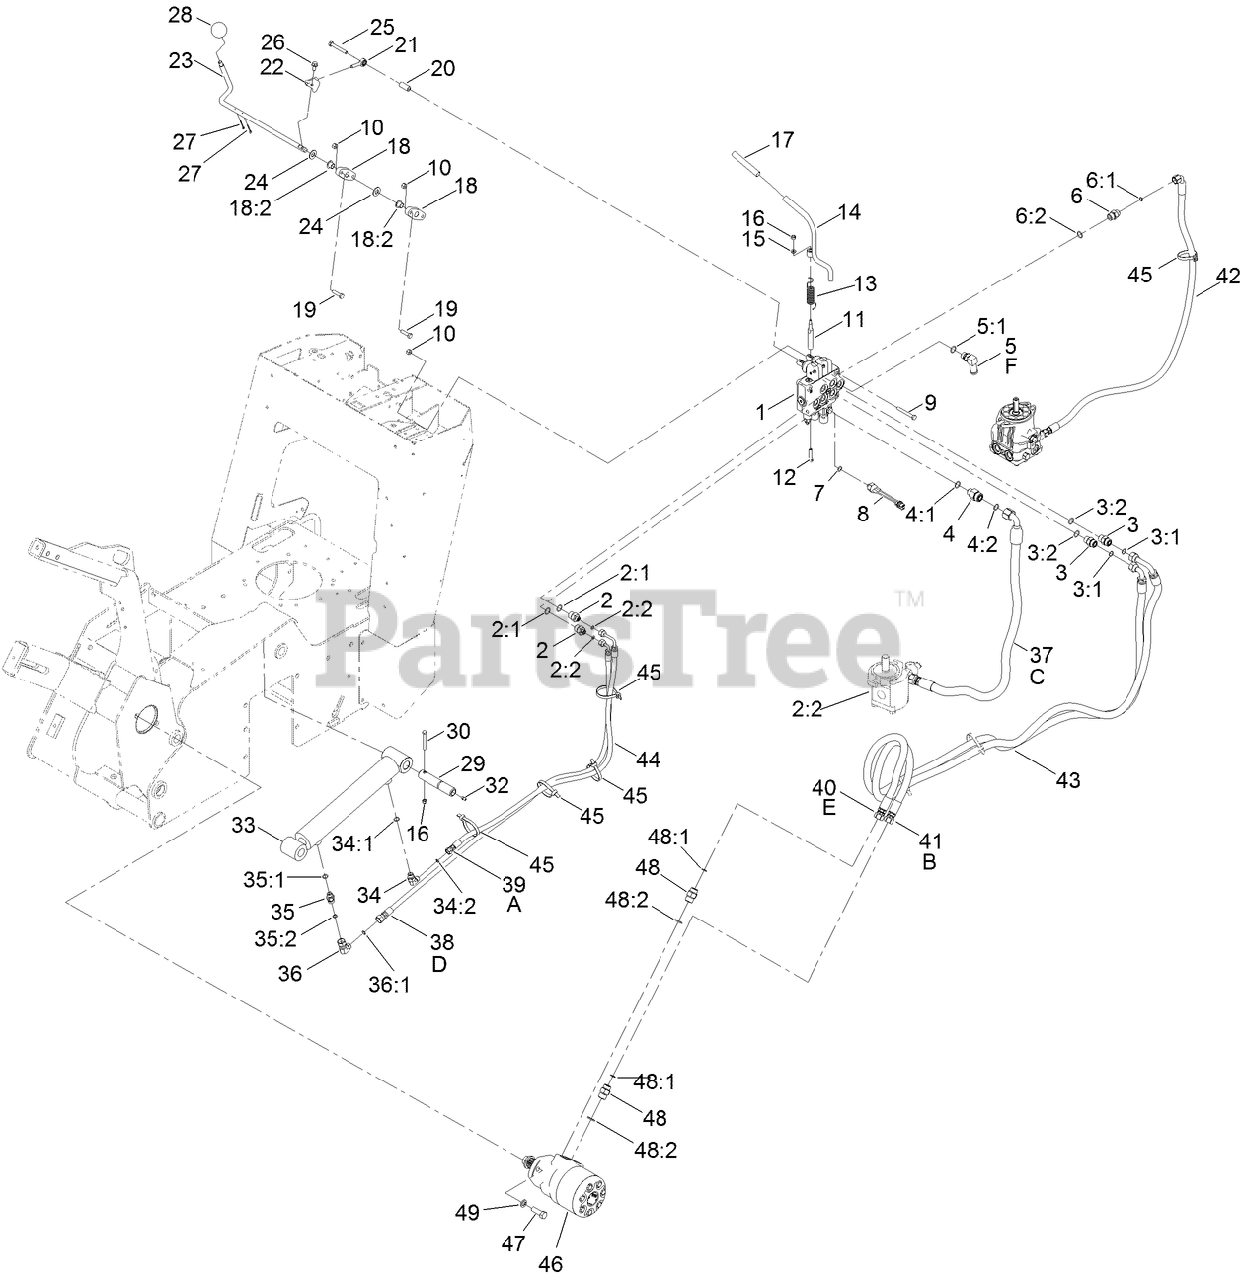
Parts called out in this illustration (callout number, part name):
1	HYD VALVE ASM
2	FITTING-STR
2:1	O-RING
2:2	O-RING
3	FITTING-STRAIGHT
3:1	O-RING
3:2	O-RING
4	FITTING-STRAIGHT
4:1	O-RING
4:2	O-RING
5	FITTING-ELBOW, 90
5:1	O-RING
6	FITTING-STRAIGHT
6:1	O-RING
6:2	O-RING
7	O-RING
8	SWITCH-BALL
9	SCREW-HH
10	NUT-LOCK, NI
11	SPACER-HIFLO
12	SCREW-HH
13	SPRING-TORSION
14	LEVER-AUXILIARY
15	WASHER-FLAT
16	NUT-LOCK, NI
17	GRIP-RUBBER
18	BUSHING ASM
18:2	BUSHING-FLANGE
19	SCREW-HH
20	SPACER
21	BEARING-ROD END
22	BRACKET-CONTROL
23	ROD-LEVER, CYLINDER
24	WASHER-FLAT
25	SCREW-HH
26	SCREW-HHF
27	PIN-COTTER
29	PIN-PIVOT
30	SCREW-HH
32	FITTING-GREASE
33	HYD CYLINDER ASM
34	FITTING-ELBOW, 90 DEG
34:1	O-RING
34:2	O-RING
35	VALVE-CHECK
35:1	O-RING
35:2	O-RING
36	FITTING-HYD, 90 DEG
36:1	O-RING
37	HOSE-HYD
38	HOSE-HYD
39	HOSE-HYD
40	HOSE-HYD
41	HOSE-HYD
42	HOSE-HYD
43	SLEEVE-PROTECTIVE
44	SLEEVE-PROTECTIVE
45	TIE-CABLE
46	HYD MOTOR ASM
47	SCREW-HH
48	FITTING-STRAIGHT
48:1	O-RING
48:2	O-RING
49	WASHER-LOCK
